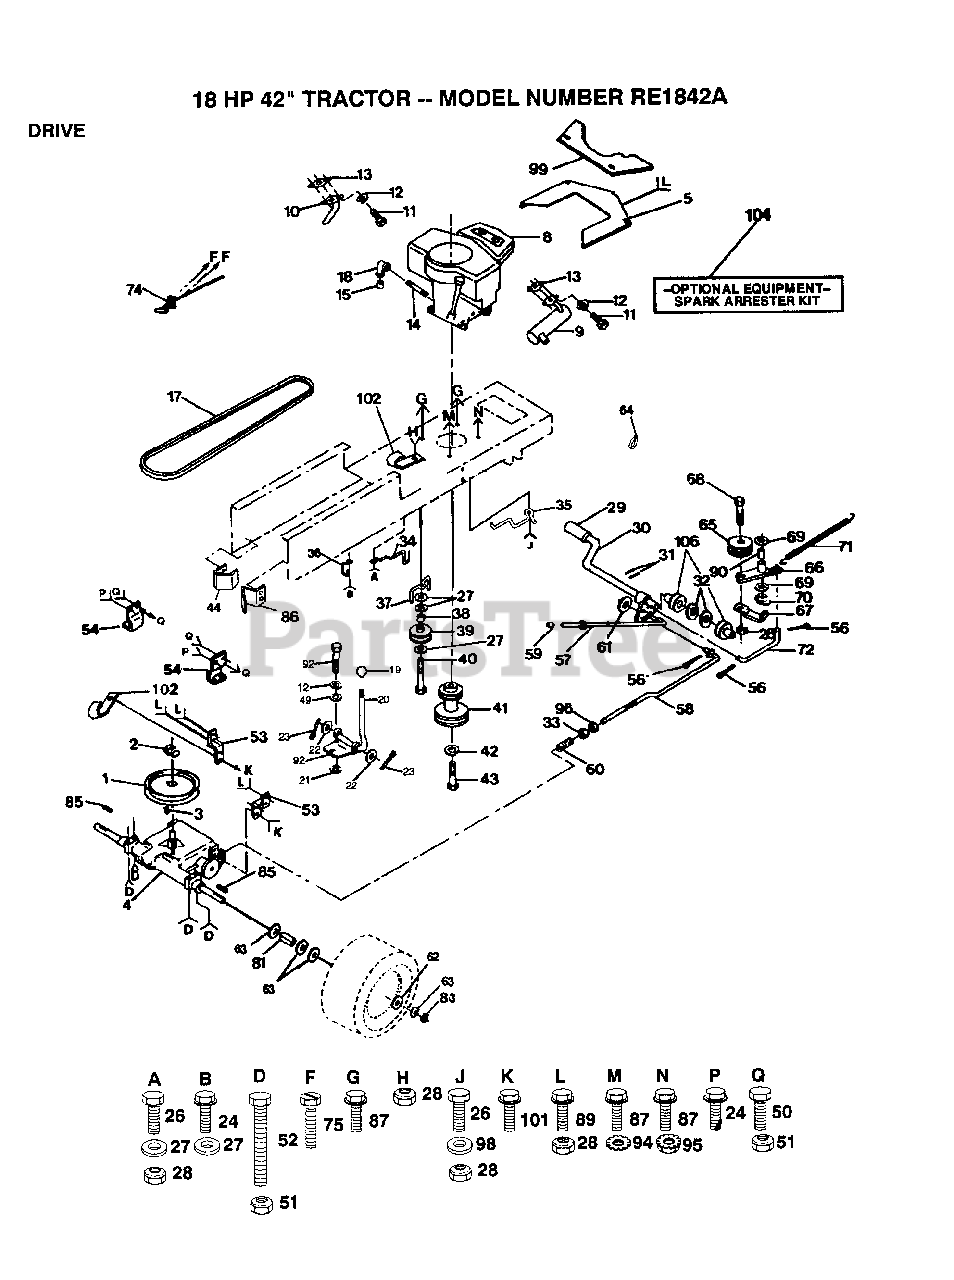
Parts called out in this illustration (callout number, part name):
1	PULLEY TRANS
5	SHIELD HEAT FRT
12	LOCKWASHER
14	PIPE NIPPLE LT
18	STREET ELBOW LT
19	KNOB T (1/2-HOLE)
20	SHIFT ROD
21	WASH-SHFT PLT LT
22	WASHER
23	PIN COTTER 1/8
24	SCREW
26	BOLT
27	WASHER
29	PEDAL COVER T
32	WASHER LT
33	NUT
34	KEEPER.BELT.ENG.L
35	KEEPER BELT ENG
37	BELT KEEPER LT
38	SPACER T
39	PULLEY.IDLER.FLAT
40	BOLT
42	LOCKWASHER
43	BOLT
44	"KEEPER,BELT LH T"
49	WASHER LT
50	BOLT
52	BOLT
53	STRAP TORQUE
54	TRANSAXLE MTG BKT
56	COTTER PIN
57	BRAKE PARK ROD
58	BRAKE ROD
59	PLUNGER CAP T
60	SPRING ROD LT
61	WASHER
62	WASHER
63	WASHER
64	MUFFLER CLAMP
66	ARM IDLER
67	RETAIN BELT
69	WASHER LT
70	KLIP RING
71	"SPRING, RETURN LT"
72	"LINK, CLUTCH T"
75	SCREW LT
81	SPACER LT
83	E-RING LT
85	SQUARE KEY
86	"KEEPER,BELT RH T"
87	SCREW LT
90	"LY, BEARING"
94	LOCKWASHER
95	NUT
96	NUT
98	WASHER
99	REAR BAFFLE T
101	SCREW
102	CLIP T
104	SPARK ARREST KIT
106	NYLON BEARING
